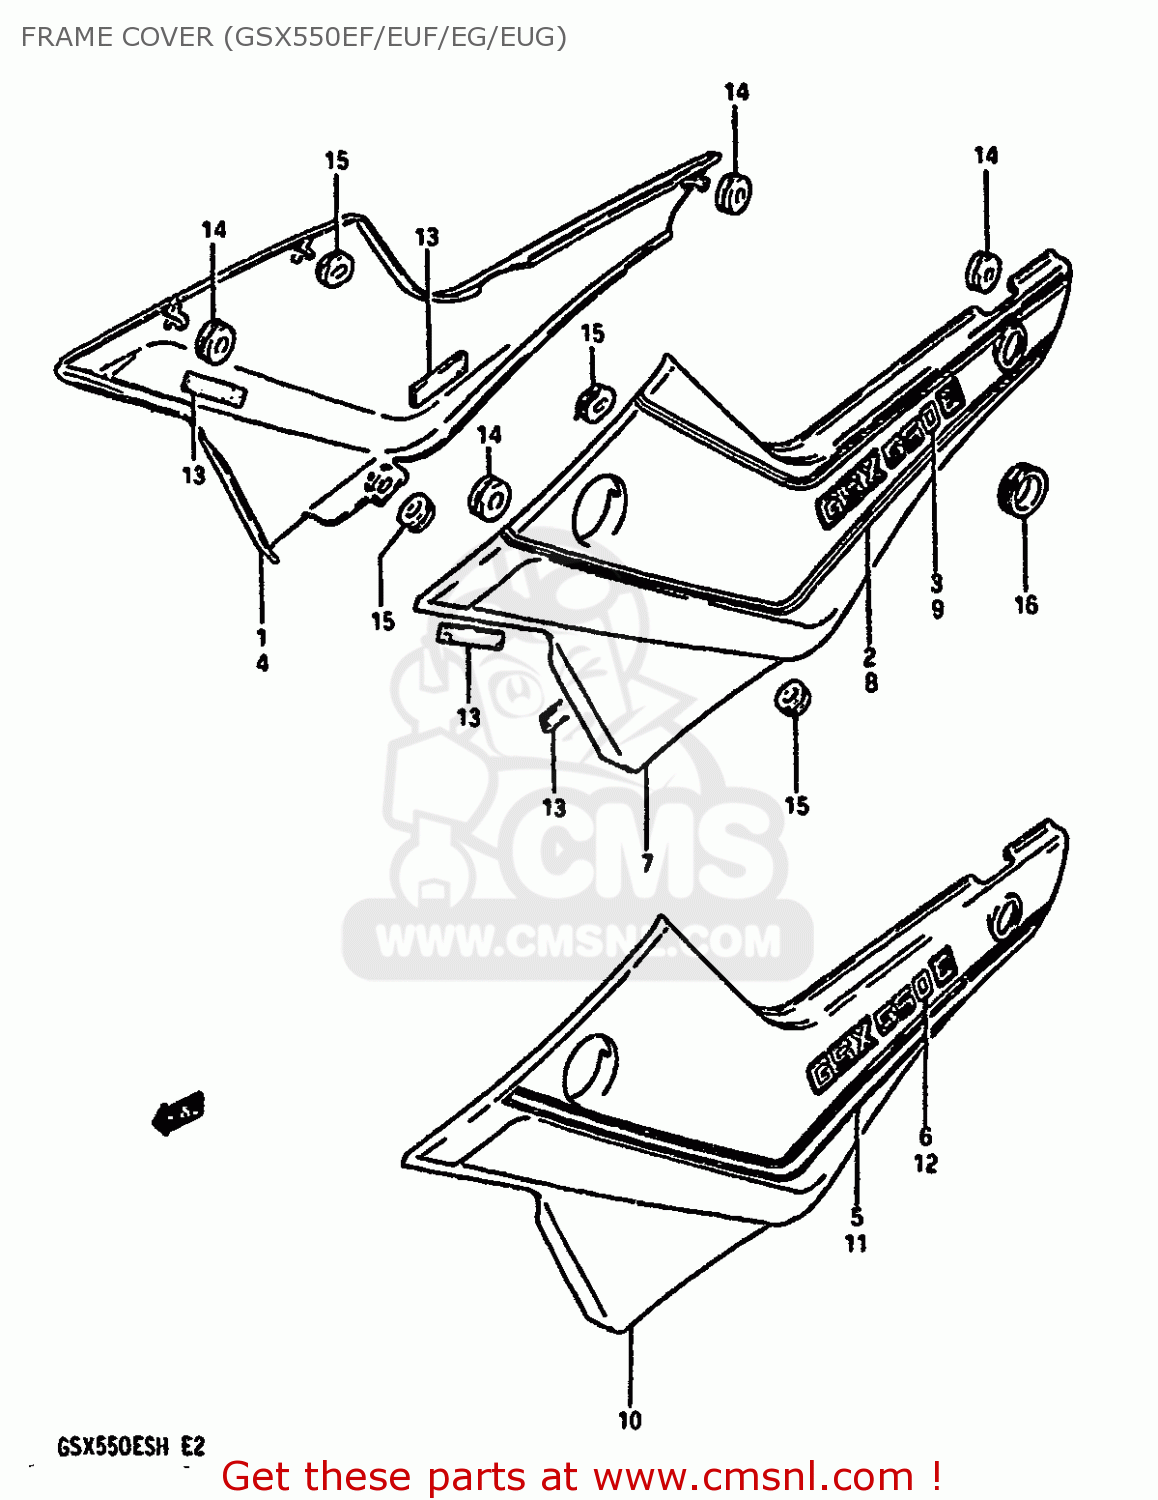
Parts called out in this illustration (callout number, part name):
1	COVER,FRAME RH
2	TAPE SET,FRAME COVER,RIGHT
3	EMBLEM
4	COVER,FRAME RH
5	TAPE SET,FRAME COVER RH
6	EMBLEM
7	COVER,FRAME LH
8	TAPE SET,FRAME COVER
9	EMBLEM
10	COVER,FRAME LH
11	TAPE SET,FRAME COVER,LEFT
12	EMBLEM
13	RUBBER,FRAME COVER
14	CUSHION
15	CUSHION
16	GROMMET,SEAT LOCK HOLE
